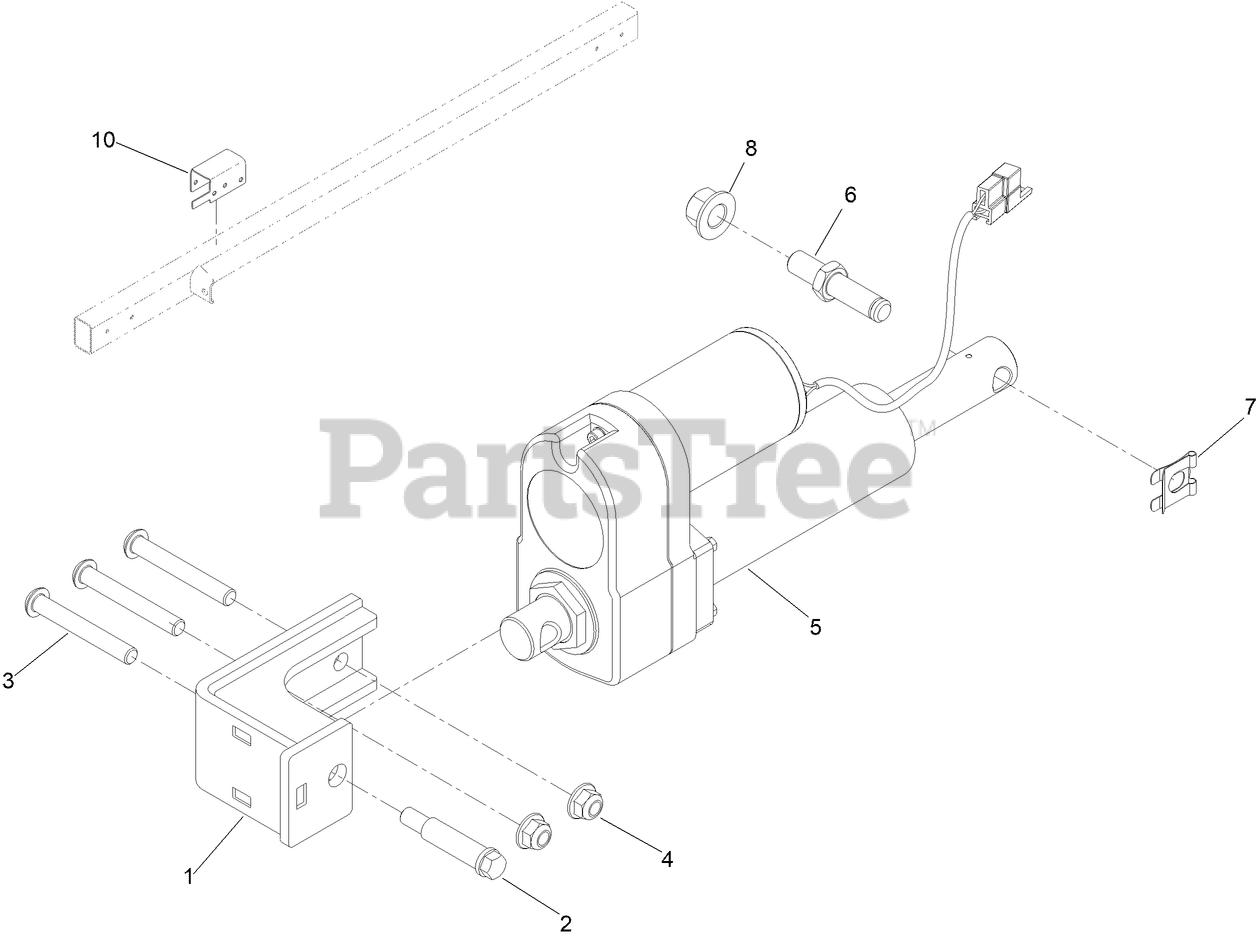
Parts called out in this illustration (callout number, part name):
1	DECK LIFT SUPPORT BRACKET [RED]
2	SCREW-SHOULDER
3	SCREW-HSBH
4	NUT-HF, NI
5	ACTUATOR-LINEAR
6	PIN-PIVOT, ACTUATOR
7	CLIP-PIN
8	NUT-LOCK
10	PLATE-TEMPLATE
